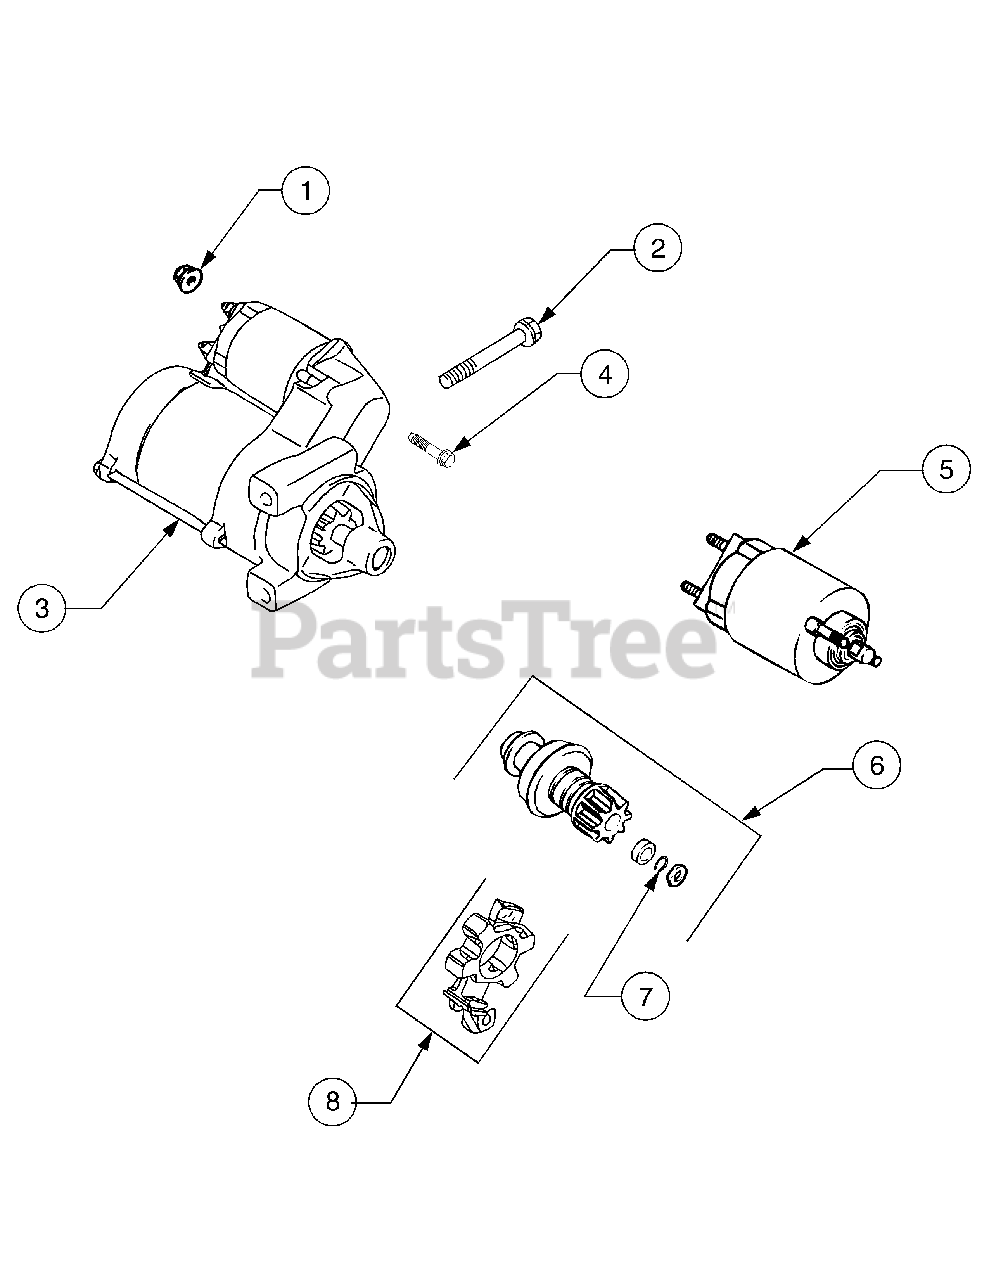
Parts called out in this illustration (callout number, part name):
1	Nut, Hex Flange M8 x 1.25"
2	Screw, Hex Flange M8 x 1.25 x 80
3	Starter, Solenoid Shift Assembly .(Includes 4-8)
4	Screw, External Torx Hd.
5	Kit, Solenoid
6	Kit, Pinion Drive (Includes 7)
7	Ring, Retainer
